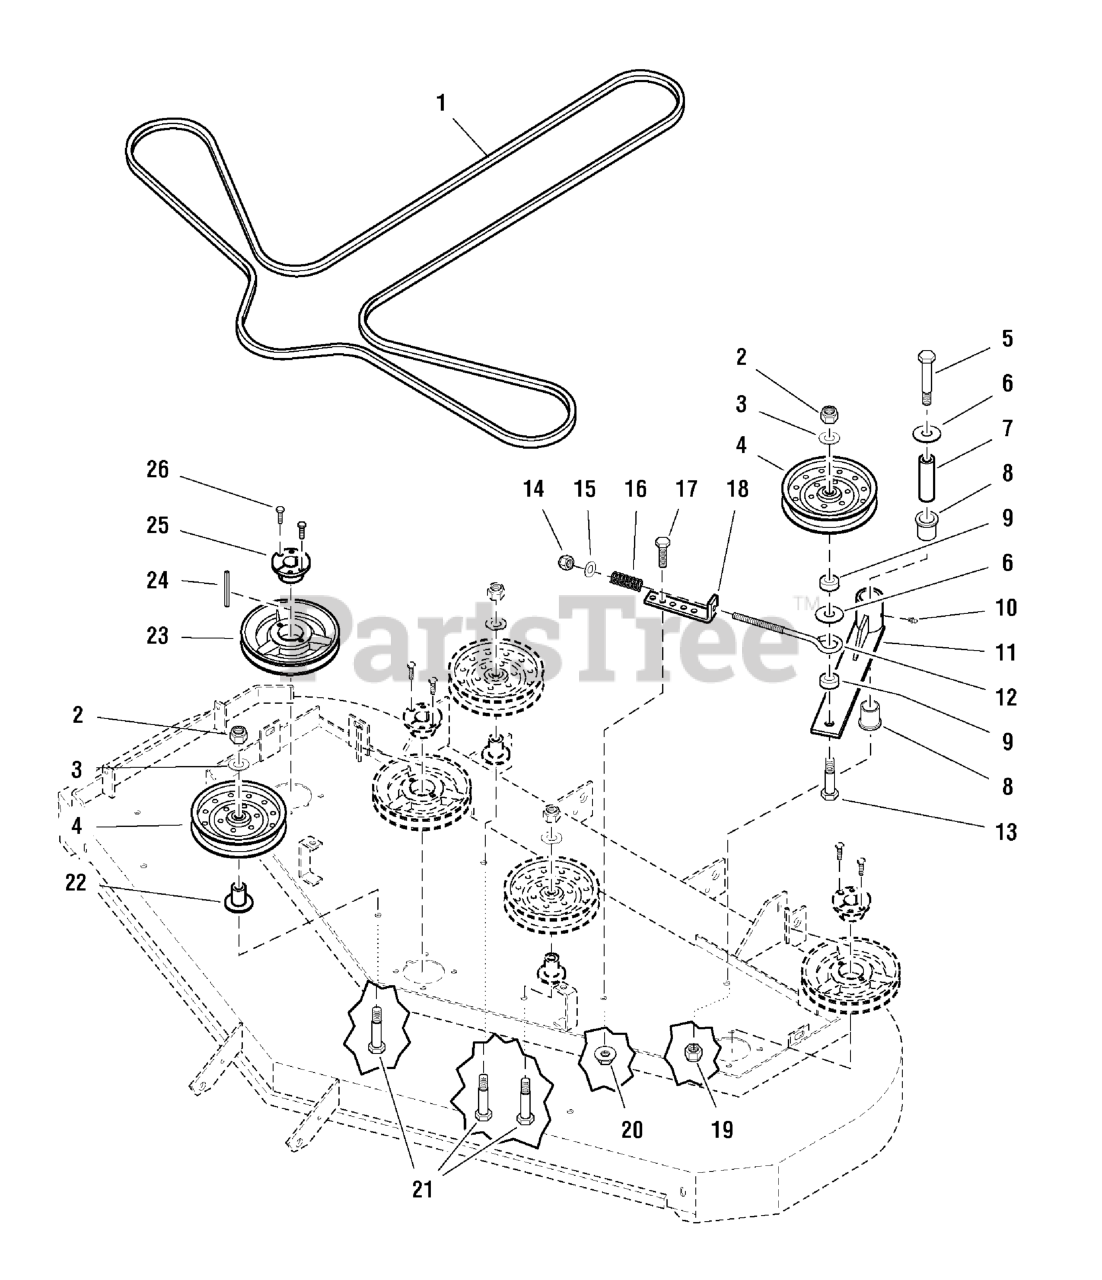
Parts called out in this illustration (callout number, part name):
1	BELT, DECK 72" 31 HP HORIZ.
2	NUT, Hex, Nylon Lock, 1/2-20
3	WASHER, 1/2 SAE
5	BOLT, 1/2-13 X 4-1/2" GD5 YZ
6	WASHER, 1/2" USSZ
7	SPACER, .52 x 1.00 x 3.50
8	BUSHING, FLANGE
9	SPACER, .52 X 1.00 X .44, CZ
10	GREASE FITTING, 1/4-28 Straight
11	WELD, IDLER ARM - RED
12	EYE BOLT, 3/8-16 X 8, 3THRD, 1EYE, CZ
13	BOLT, 1/2-20 X 3" GD5 YZ
14	NUT, 3/8-16 HEX NYLON LOCK
15	WASHER, 3/8 SAE
16	SPRING, COMPRESSION 2" MEDIUM
17	BOLT, 3/8-16 X 1" GD5 CZ
18	SPRING ANCHOR
19	NUT, 1/2-13 HEX NYLON LOCK
20	NUT, 3/8-16 Hex Large Serrated Flange
21	BOLT, 1/2-20 X 3-1/2" GD5 YZ
22	IDLER PULLEY MOUNT - RED
23	PULLEY, SPINDLE, BH 72
24	Key, 1/4" Sq. x 2-1/2"
25	BUSHING, Tapered Hub
26	BOLT, 1/4-20 X 1" GD5 CZ
